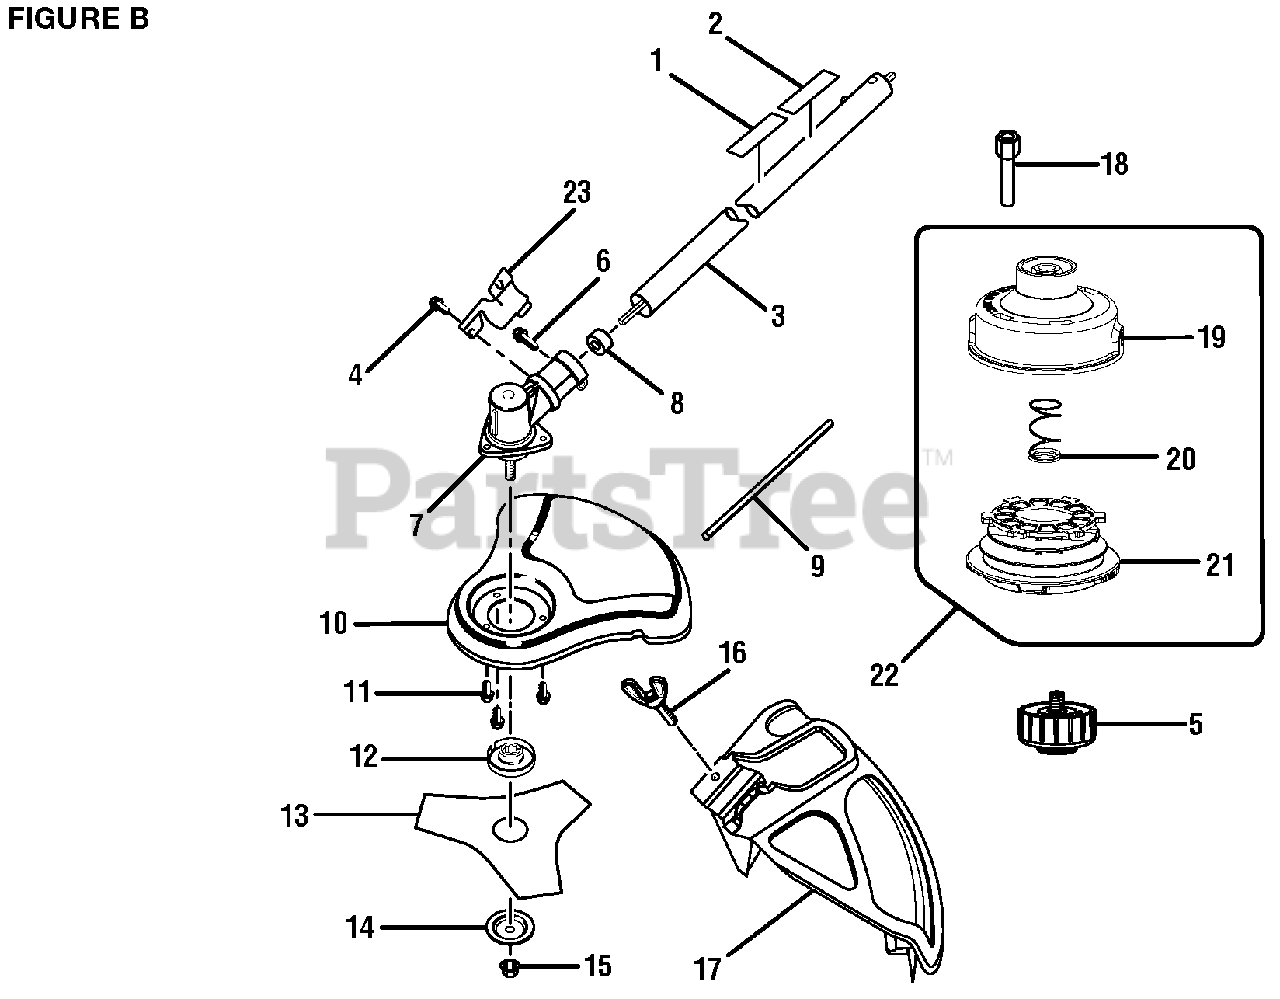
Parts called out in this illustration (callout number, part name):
1	Expand-it Label
2	Brushcutter Safety Label
3	Straight Shaft Assembly
4	Screw (10-24 x 5/8 in.)
5	Spool Retainer
6	Screw (1/4-20 x 1-1/4 in.)
7	Gear Head
9	Gear Head Locking Tool
10	Brushcutter Guard
11	Screw (10-24 x 1/2 in.)
12	Flanged Washer
14	Cupped Washer
15	Blade Nut
16	Screw (1/4-20 x 1-1/4 in.)
17	Grass Deflector Assembly
19	String Head Housing
22	String Head Assembly
